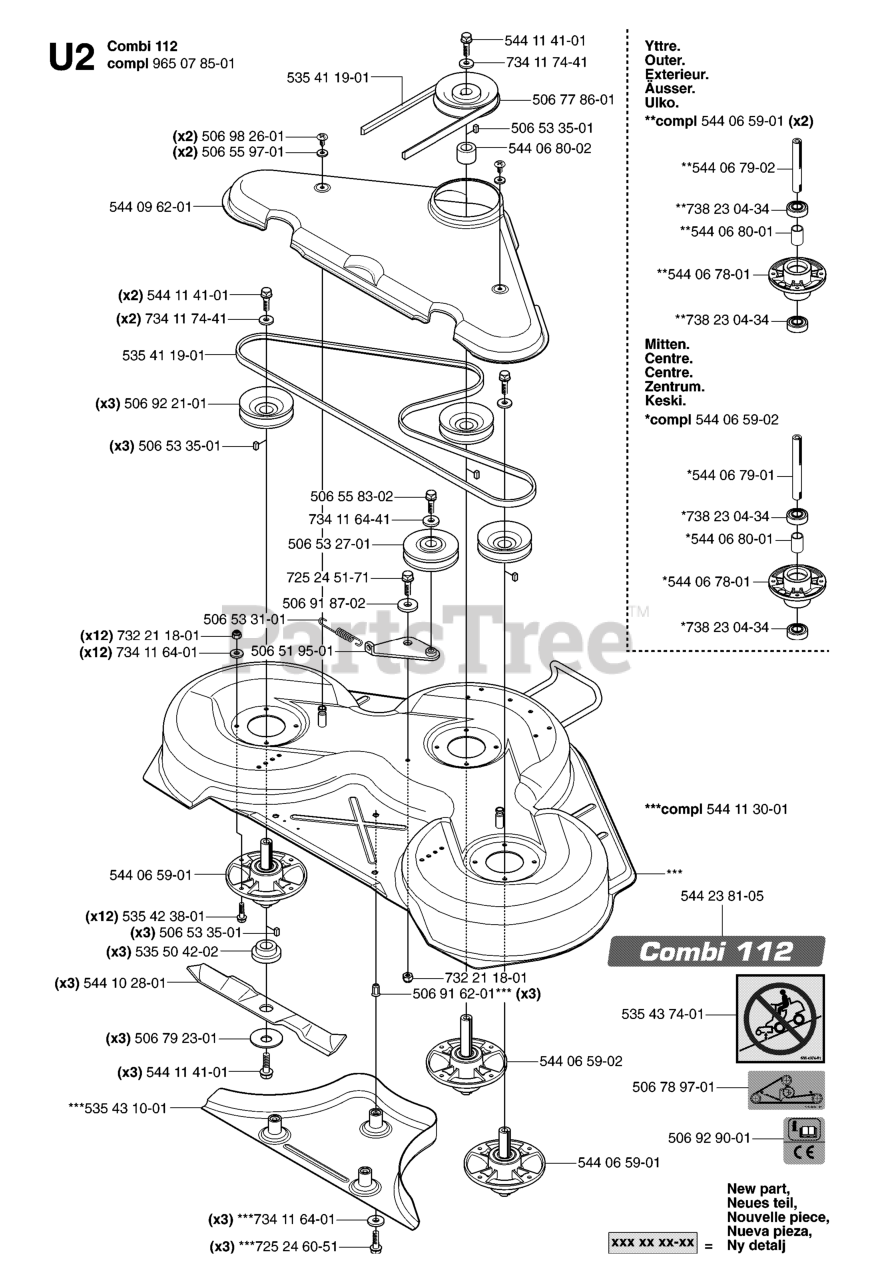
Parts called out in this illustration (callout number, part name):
1	LOWER HOUSING
2	HOUSING UPPER 70255
3	SEAL.LIP.H-G.(9008000-0128)
4	RING RETAINING 2003016
5	RING.RETAINING.(2003052)
6	BALL BEARING
7	CRADLE BEARING
8	BEARING, THRUST 50551
9	SWASHPLATE (2003087)
13	BLOCK, CYL ASSY
14	TRUNNION ARM
17	SLOT GUIDE
18	SHAFT, MOTOR
19	BEARING, THRUST 50552
23	BLOCK, CYL ASSY
25	BYPASS ACTUATOR
26	CENTER SECTION ASS'Y KIT
28	RETAINING RING
34	ELEMENT, OIL FILTER
35	BYPASS ARM
36	RETAINING RING 44870
37	ACTUATING ARM
38	ACTUATING PIN 44891
39	BOLT 5/16-24 X 1-3/4
40	LOCKNUT, HEX 5/16-24
41	BRAKE ROTOR 70135 HYDRO-GEAR
43	WASHER .34X.88X.06.44130
44	KIT SVC DIFFRENTIAL 70130
52	WASHER.HYDRO-GEAR 44875
53	SEAL.HYDRO.53901
56	SHAFT.INPUT.50005
58	BOLT #44876
62	CONTROL ARM 50254
63	DAMPENER PUCK
64	SCREW.SET.50018
68	SPRING HELICAL COMP 50277
69	STUD 5/16-24 50284
83	JACK SHAFT ASSY
89	WASHER 50132
90	SLEEVE.BEARING 50118
91	RP SEAL, WIPER
92	SPRING 2003014
113	CAP, VENT ASSY
114	O-RING KIT 70110
119	SPACER.HYDRO GEAR 50278
134	NUT.CAS.HYD.44142
135	ID DOT HYDD
139	SPRING, COMPRESSION 50431
140	NUT, HEX 5/16-24
